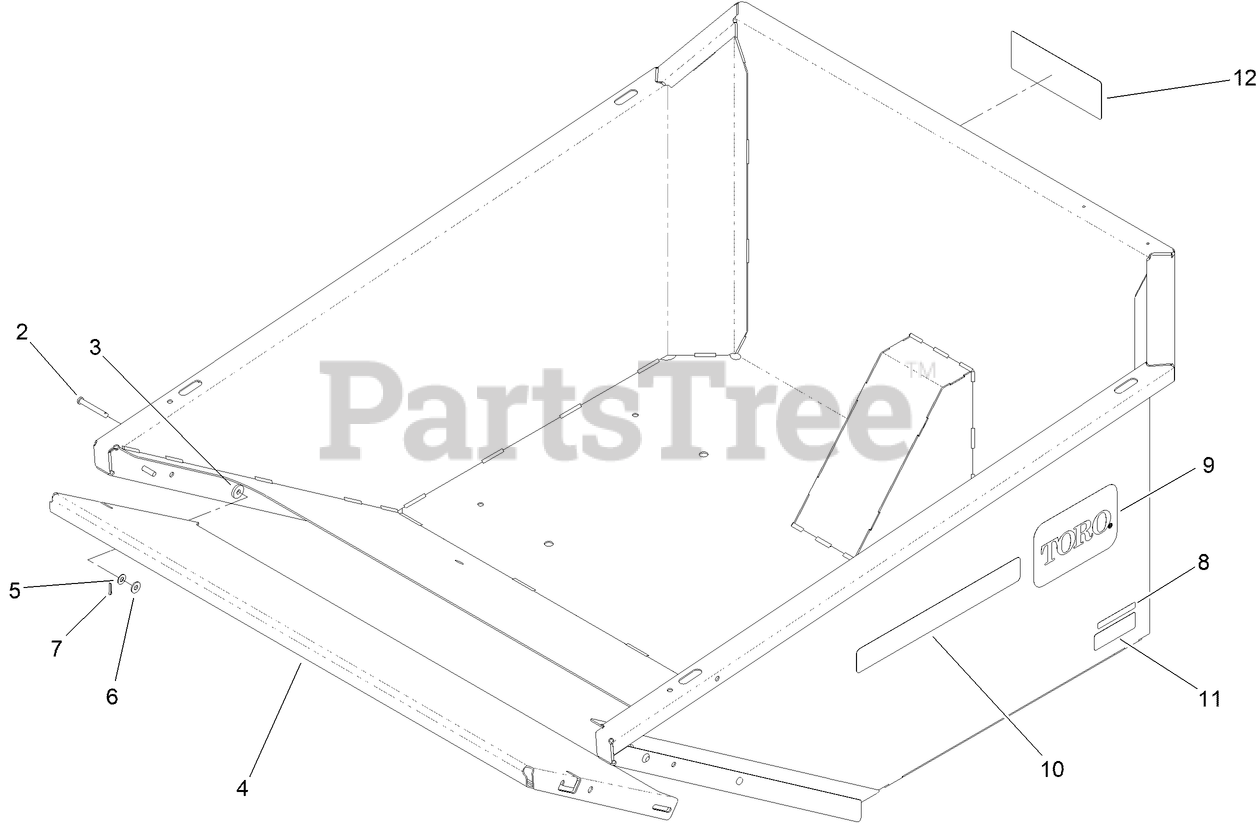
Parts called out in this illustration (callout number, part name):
2	PIN-CLEVIS
3	WASHER
4	MULCH DOOR [BLACK]
5	WASHER-NYLON
6	WASHER
7	PIN-COTTER
8	DECAL-WARNING
10	DECAL - MULCH FORCE
11	DECAL-WARNING, PINCH POINT
12	DECAL-LOAD CAPACITY
